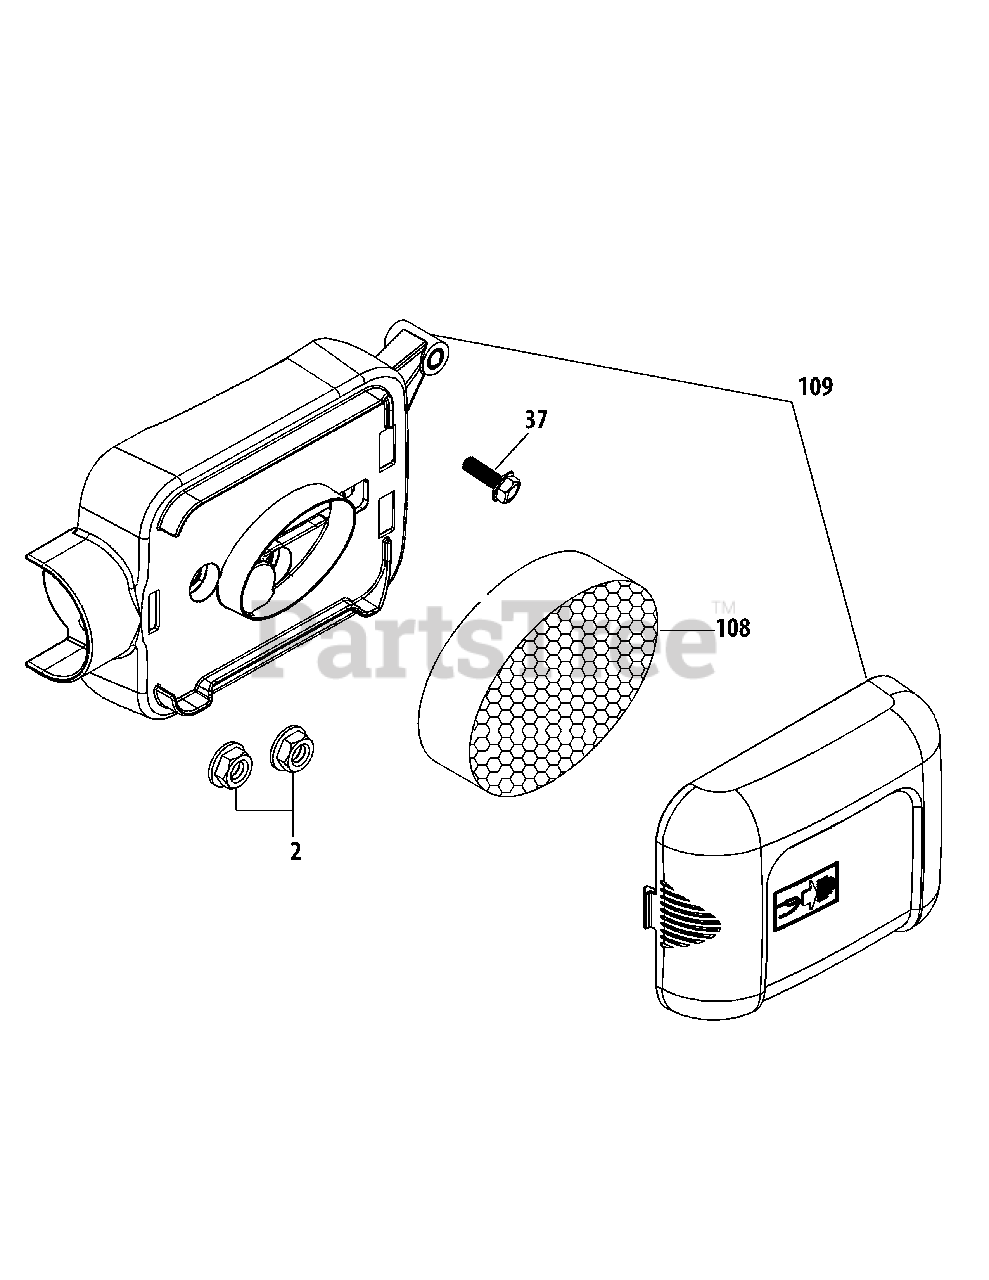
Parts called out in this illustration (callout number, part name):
2	Nut M6X10Mm
37	Bolt M6X30
108	Air Filter Element, Oval
109	Air Cleaner Housing Asm
